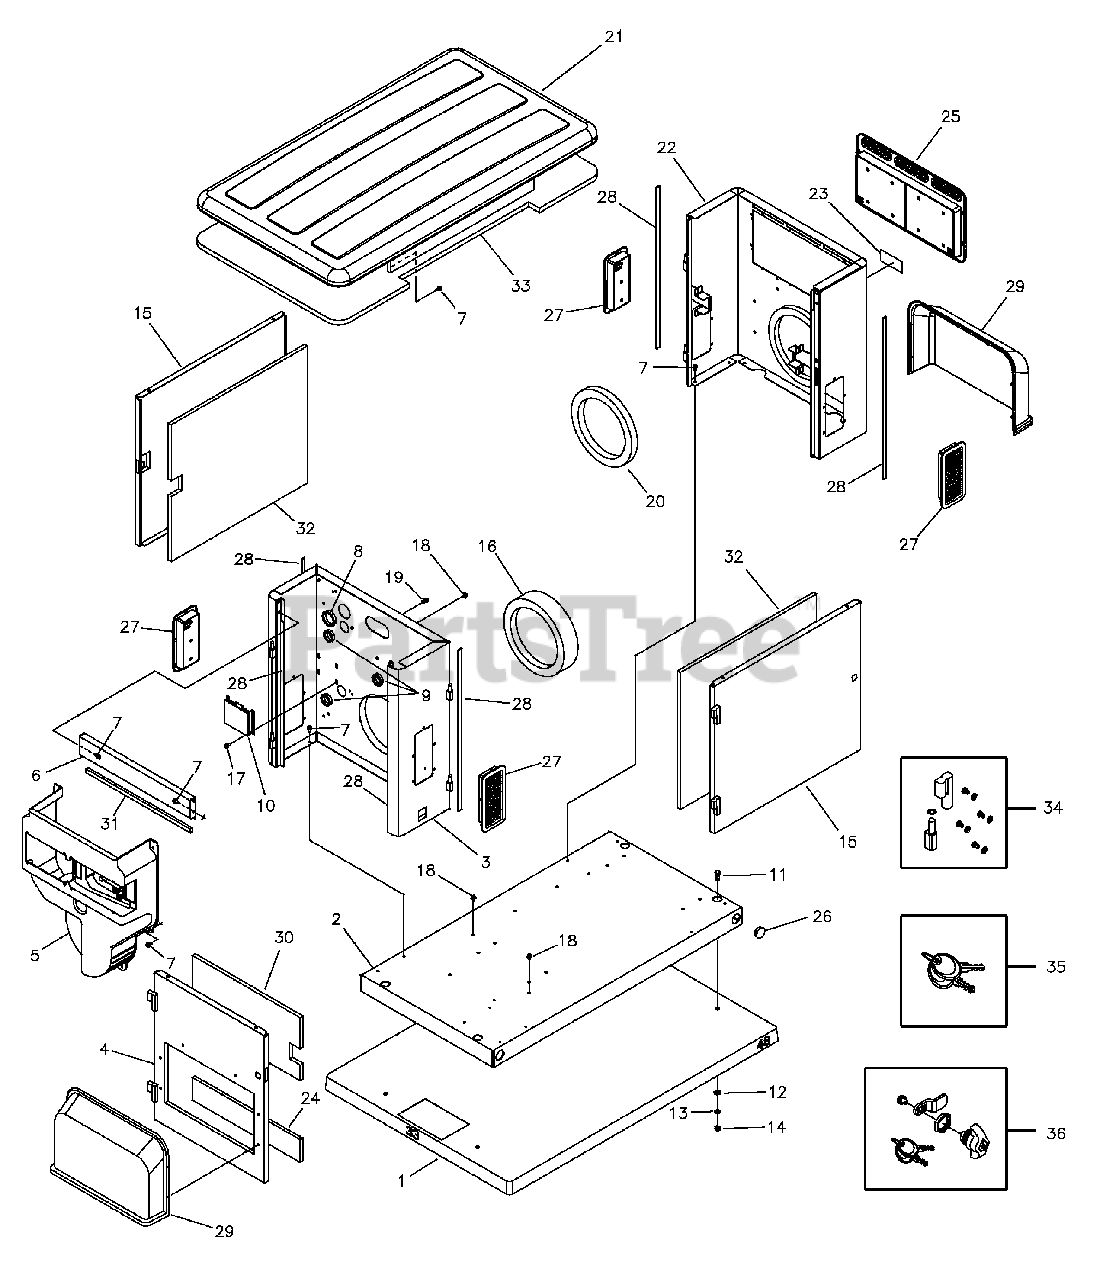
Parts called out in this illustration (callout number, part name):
3	BULKHEAD, Engine
7	BOLT
10	REGULATOR, Voltage
11	*CAPSCREW, Hex Head, 3/8-16 x 1
12	*WASHER, Flat, 3/8 - M10
13	*WASHER, Lock, 3/8
14	*NUT, 3/8-16
16	SEAL, Foam
20	SEAL, Foam
22	BULKHEAD, Alternator
29	COVER, Air Intake
